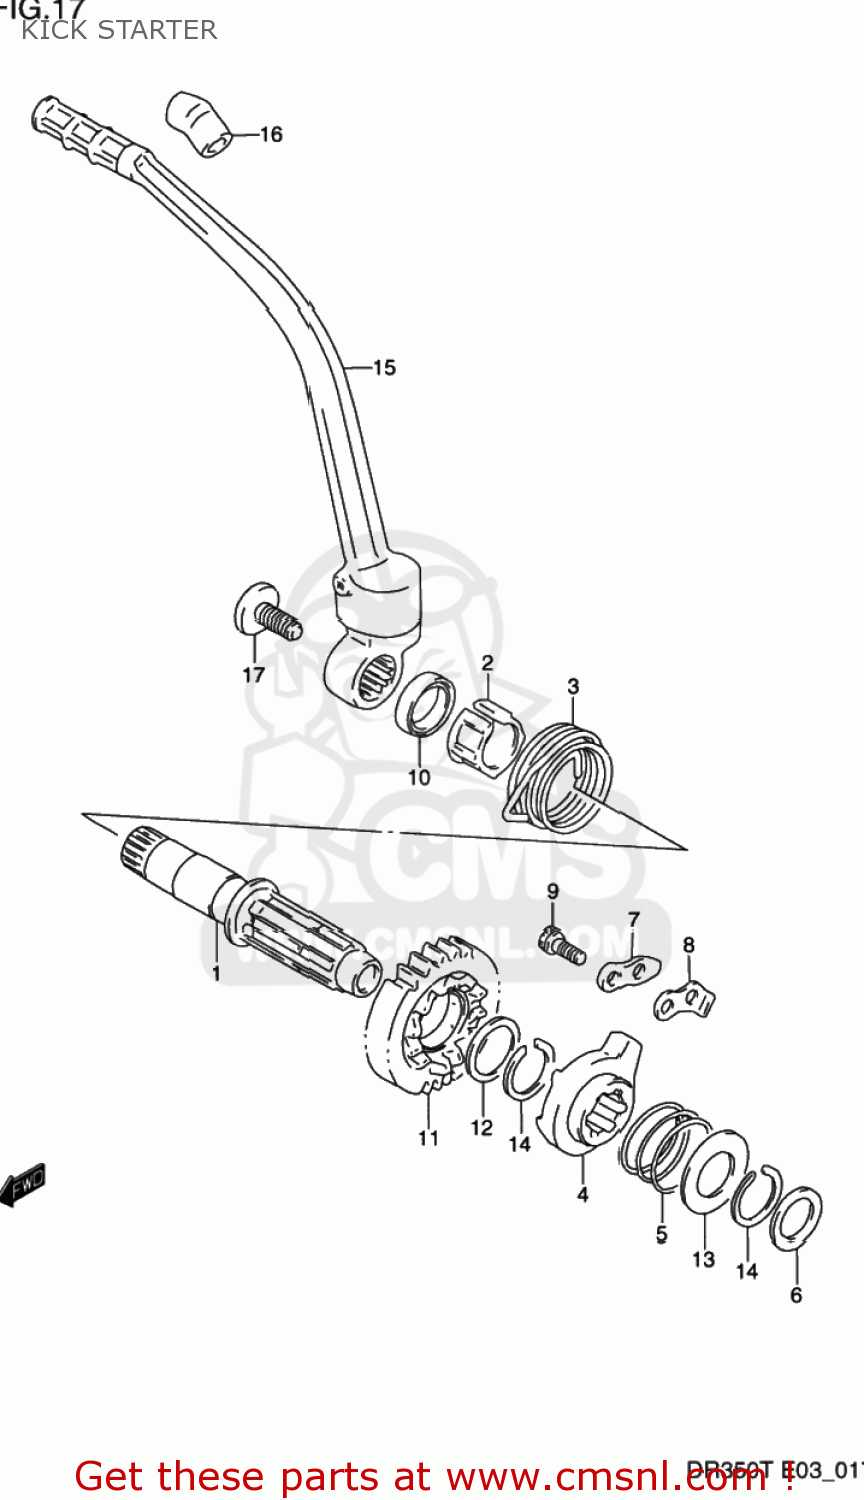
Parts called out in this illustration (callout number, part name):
1	SHAFT,KICK STARTER
2	GUIDE,KICK STARTER SFT SPRING
3	SPRING
4	STARTER,KICK
5	SPRING
6	WASHER,THRUST
7	GUIDE,KICK STARTER
8	STOPPER,KICK STARTER
9	BOLT,KICK START STOPPER
10	SEAL,OIL(20X27X6)
11	GEAR,KICK STARTER NO.2
12	SHIM
13	WASHER,THRUST
14	CIRCLIP
15	LEVER ASSEMBLY,KICK STARTER
16	COVER,KICK STARTER LEVER
17	BOLT(8X14)
